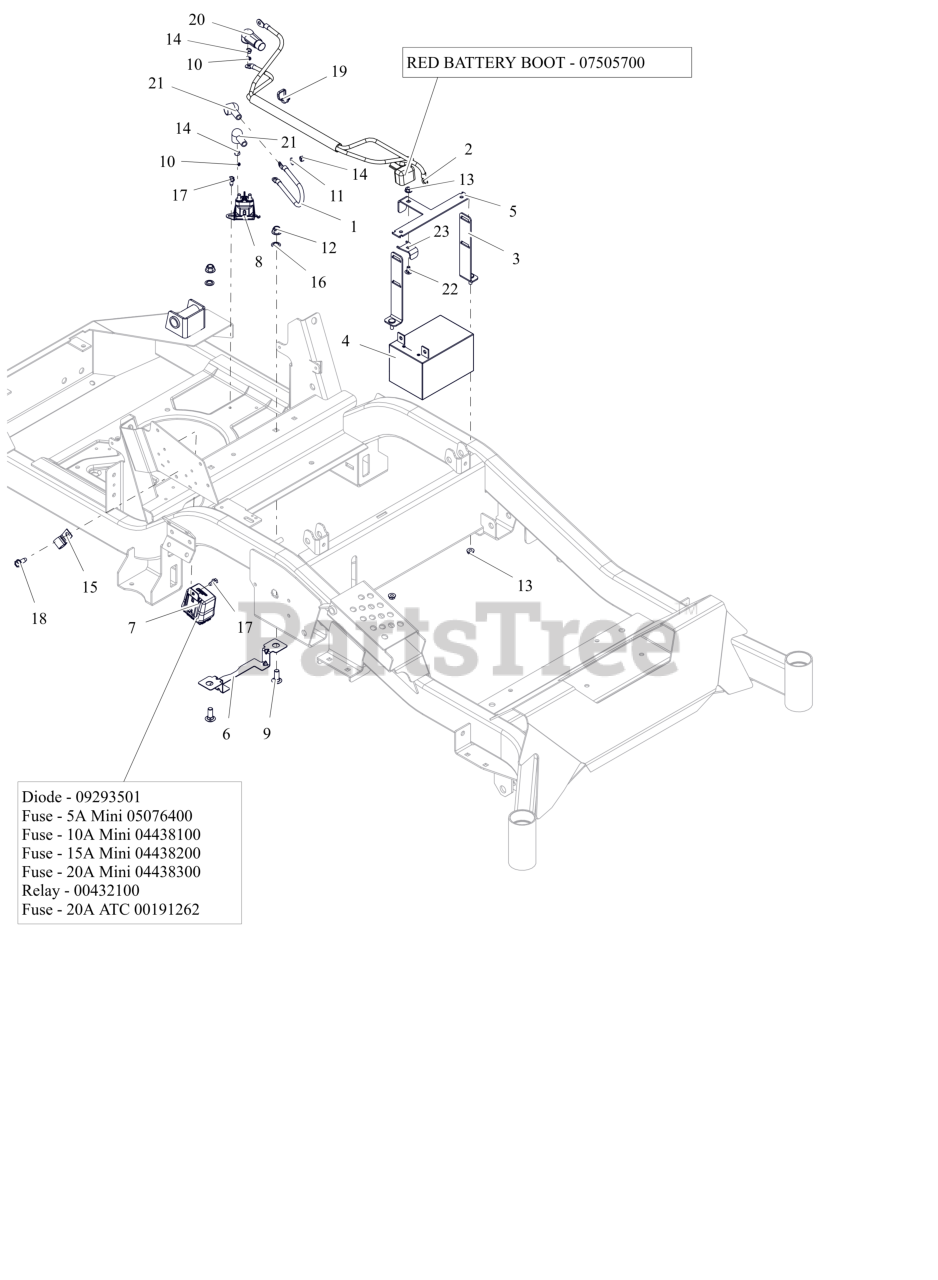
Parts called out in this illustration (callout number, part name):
1	CABLE, POS W/(2)1/4 RING 9.0LG
2	HARNESS, BATTERY HD
2	INSULATOR
3	WMT,BATTERY MOUNT HOLD DOWN
4	BATTERY, 12V 12A -190CCA
5	BRKT, BATTERY TIE DOWN
6	GUARD, ELECTRICAL HARNESS
7	HARNESS, WIRE
7	DIODE, CONNECTOR SHELL
7	FUSE, 5 AMP MINI-ATC
7	FUSE,10 AMP MINI-ATC
7	Fuse, 15 AMP MINI-ATC
7	FUSE,20 AMP MINI ATC
7	RELAY,MICRO5 TERML W/RESISTOR
7	FUSE, 20 AMP BLADE S/O
8	SOLENOID, STARTER (SEALED)
9	BLT, RHSN .38-16X1.00 G5 ZCC
10	WSHR,LK-EXT.262X.502X.026 ZCC
11	WSHR,LK-REG .312X.078 ZCC
12	NUT,NYL-FLG .38-16 GF ZCC
13	NUT-LK-TOP-FLG .250-20 GF ZCC
14	NUT-STD M6-1.0 ZCC
15	J-CLAMP
16	NUT-PUSH .38 DIA. PAL ZINC
17	SCR-TAP .25-20X.50 HWH ZCC
18	SCR,TAP .312-18X.75 HWH TR ZCC
19	CABLE TIE W/ TREE (.25 HOLE)
20	BOOT, .65ID POS
21	BOOT, EYELET TERMINAL
22	BLT, RHSN .25-20X.500 G5 ZCC
23	BRKT, BATTERY HOLD
